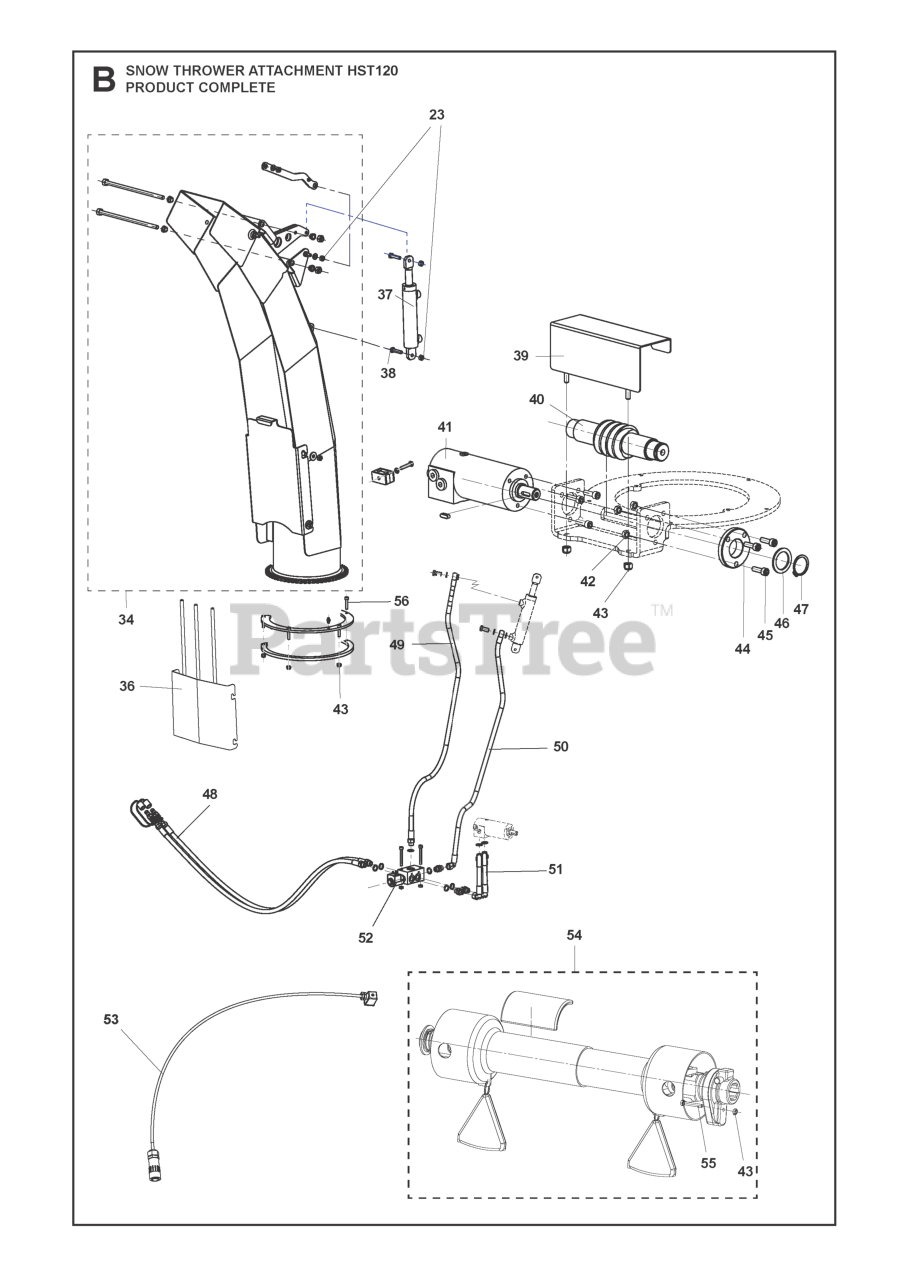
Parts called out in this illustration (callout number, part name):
23	NUT LOCK - M8, NYLOCK
45	SCREW MC6S 6X20
56	SCREW IHSCM
